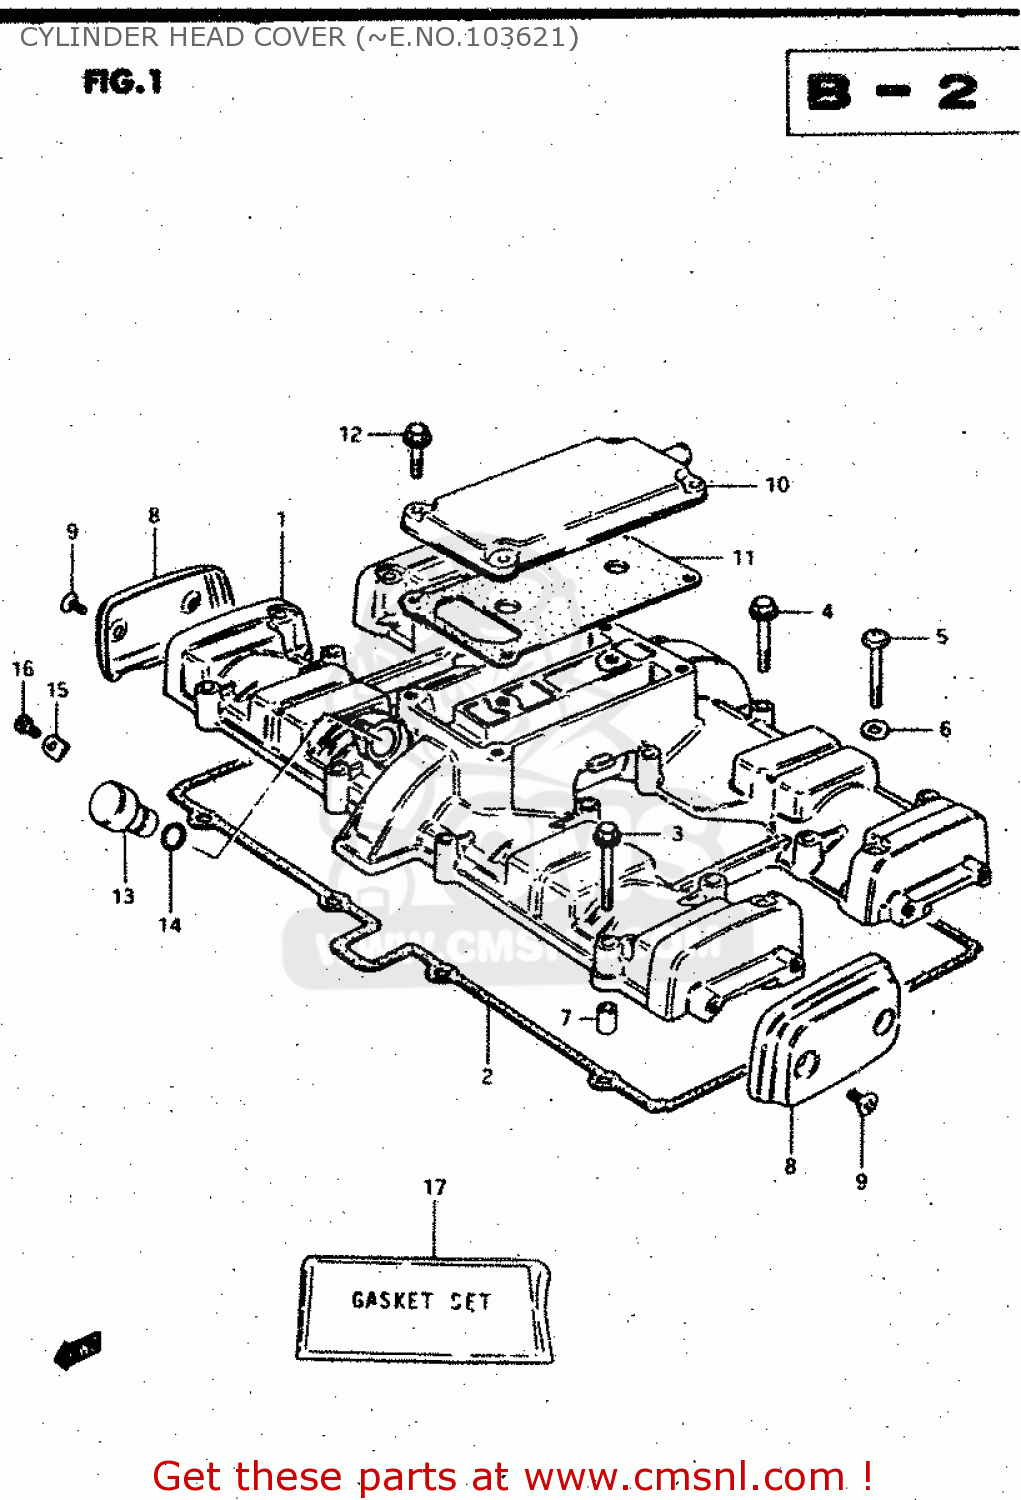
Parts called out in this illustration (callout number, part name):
1	COVER,CYLINDER HEAD
2	GASKET,CYLINDER HEAD COVER (MCA)
3	BOLT
4	BOLT 6X35
5	SCREW 6X40
6	WASHER
7	PIN
8	CAP,CYLINDER HEAD COVER
9	SCREW(5X12)
10	COVER,BREATHER
11	GASKET (MCA)
12	BOLT,REAR
13	PLUG,TACH GEAR SLEEVE HOLE
14	SEAL,TACHOMETER DRIVEN
15	PLATE,TACH DRIVE GEAR SLEEVE
16	SCREW(5X12)
17	GASKET SET
